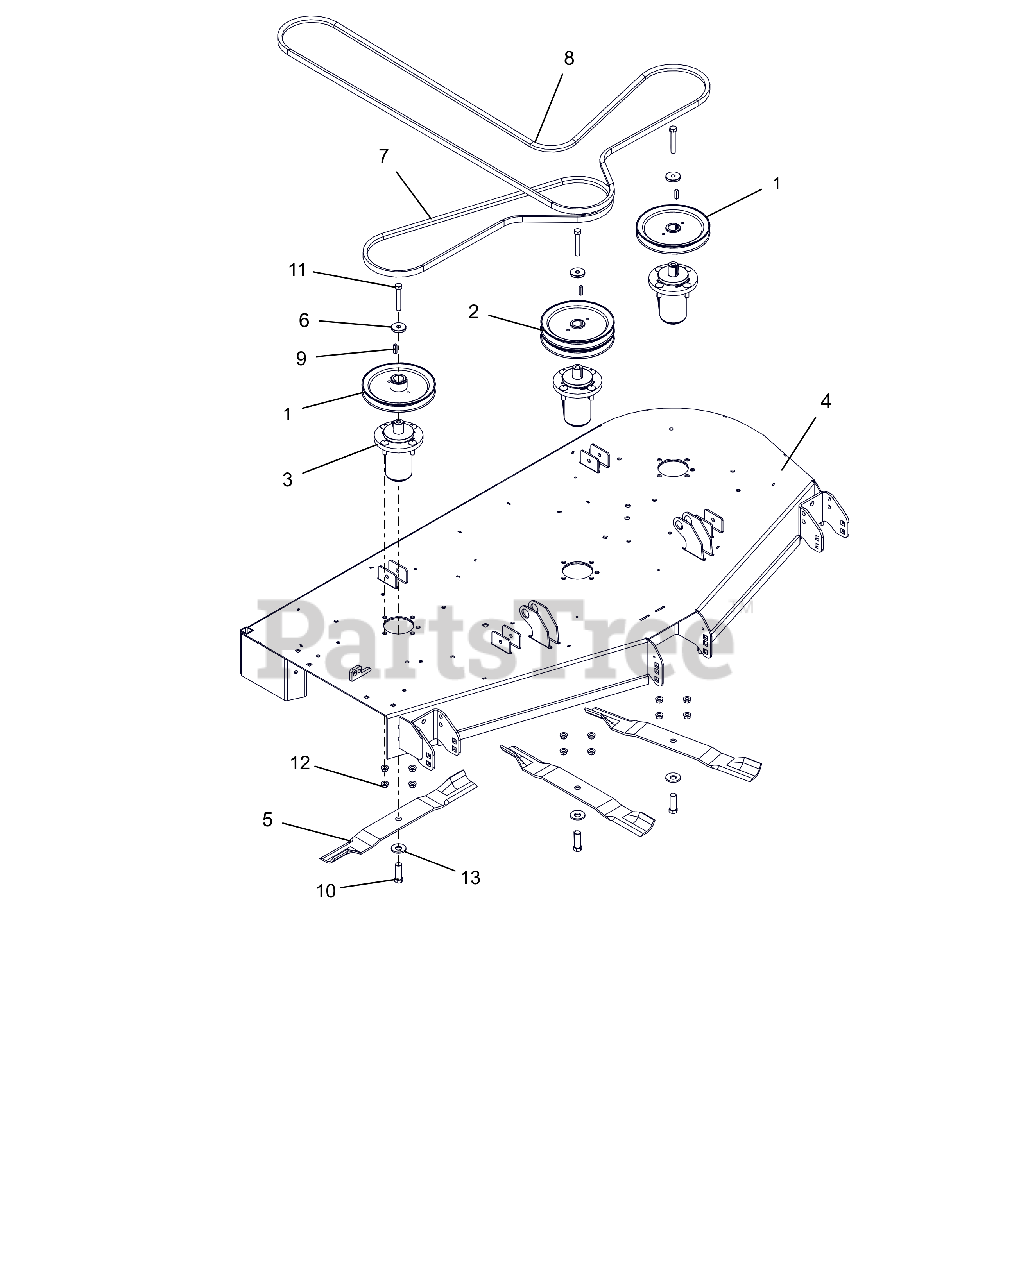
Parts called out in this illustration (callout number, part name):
1	PULLEY, V-7.50 OD X 1"ID
2	PULLEY, DOUBLE 1"X7.50"&7.50" (BLACK)
3	ASM, MAINT FREE ALUM SPINDLE
4	WLDMT, 60" CE SIDE DISCH DECK (ORANGE)
5	BLADE, 20.5"
6	RETAINER, SHEAVE
7	V-BELT, B-COGGED
8	V-BELT, HB SECTION
9	KEY, SQ .25X.25X1.00 RC 40-50
10	BLT, HEX .62-18X1.75 G8 ZCC
11	BLT, HEX .38-16X2.75 G8 ZCC
12	NUT-LK-CTR-FLG .375-16 GF ZCC
13	WSHR-BLVL .669X1.535X.138
